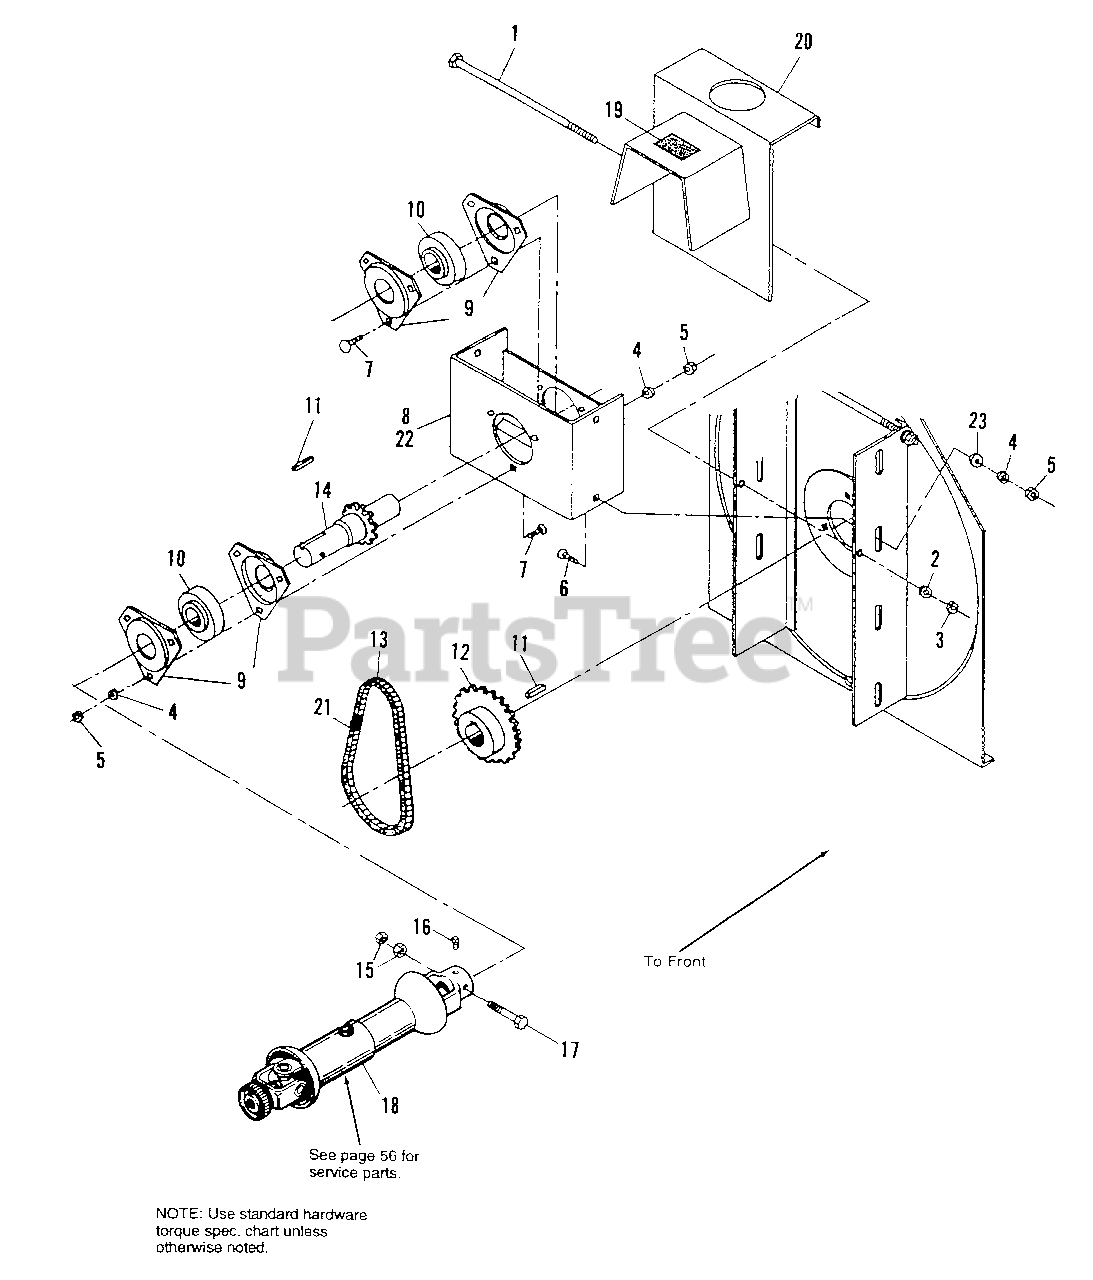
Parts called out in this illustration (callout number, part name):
1	CAPSCREW, Hex Hd., 1/4-20 x 7-1/2
2	LOCKWASHER, 1/4
3	NUT, Hex, 1/4-20
4	LOCKWASHER, 5/16
5	NUT, Hex, 5/16-18
6	BOLT, Carriage, 5/16-18 x 3/4
7	BOLT, Carriage, 5/16-18 x 5/8
8	BOX ASSY., Reduction
9	BEARING, Flange
10	BEARING, 1" I.D. w/Locking Screw
11	KEY, Parallel, Plain, 1/4 x 1/4 x 1-1/4
14	SHAFT, Assy., Drive, w/Sprocket
15	NUT, Hex Lock, 1/4-20
16	SETSCREW, Sq. Hd., 5/16-18 x 5/8
17	CAPSCREW, Hex Hd., 1/4-20 x 2-1/2
18	DRIVE SHAFT
19	DECAL, Danger
20	SHIELD, P.T.O.
21	MASTER LINK, Chain #40
22	BOX, Reduction
23	WASHER
